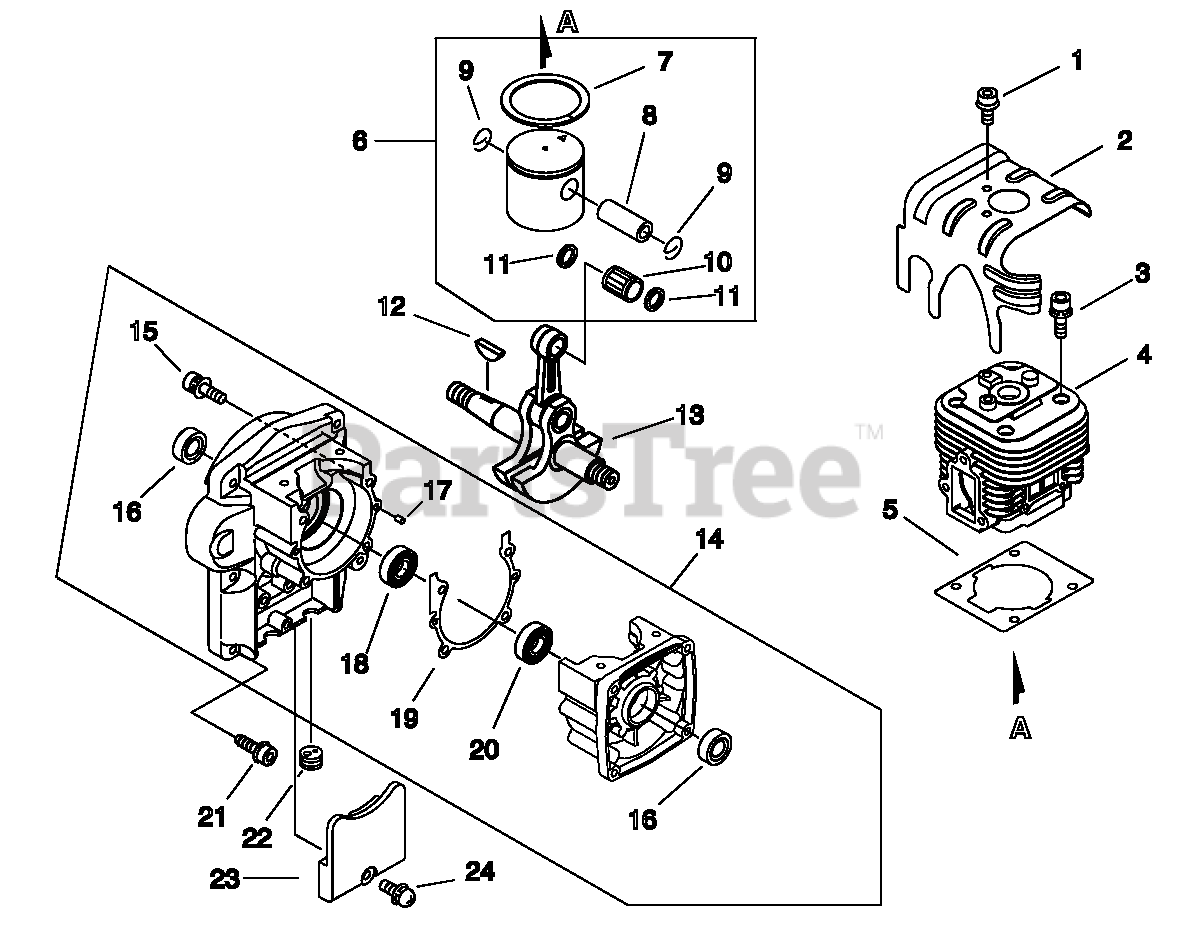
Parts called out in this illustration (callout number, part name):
1	SCREW - 5X8
2	SHIELD, CYLINDER
3	SCREW - 5X22
4	CYLINDER
5	GASKET, CYLINDER
6	PISTON KIT
7	RING, PISTON
8	PIN, PISTON
9	RING, RETAINING - 8
10	BEARING, NEEDLE
10	BEARING, NEEDLE - 10
11	SPACER, PISTON
12	KEY - 3X14
13	CRANKSHAFT ASSY
14	CRANKCASE KIT
15	SCREW - 5X40
16	SEAL, OIL
17	PIN - LOCATING
18	BEARING, BALL - 6302
19	GASKET, CRANKCASE
20	BEARING, BALL - 6202
21	SCREW - 5X32
23	COVER, DUST
24	SCREW - 5X18
